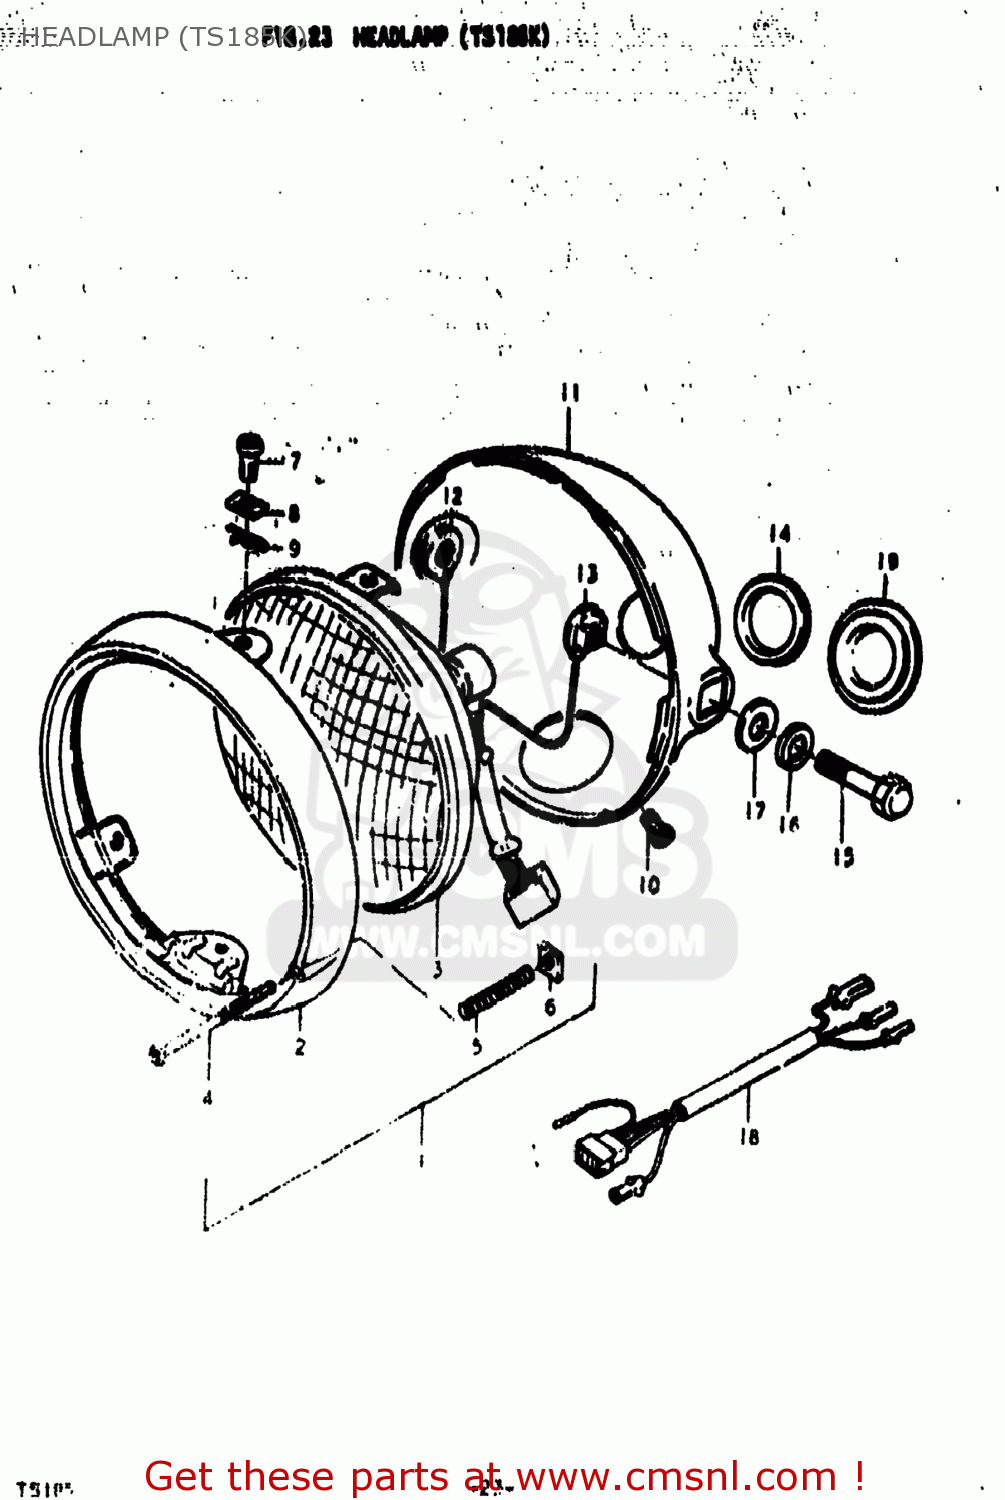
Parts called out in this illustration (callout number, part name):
1	HEADLAMP ASSEMBLY
2	RIM,HEADLAMP
3	LAMP UNIT
4	SCREW,HEADLAMP ADJUST
5	SPRING,HEADLAMP ADJUST
6	NUT,HEADLAMP ADJUSTER
7	SCREW,LENS
8	NUT,ADJUSTING
9	CUSHION,HEADLAMP
10	SCREW(5X12)
11	HOUSING,HEADLAMP
12	SPACER,HEADLAMP HOUSING
13	SPACER,HEADLAMP HOUSING
14	GROMMET,HEADLAMP HOUSING
15	BOLT
16	LOCK WASHER
17	WASHER
18	WIRE
19	CAP
